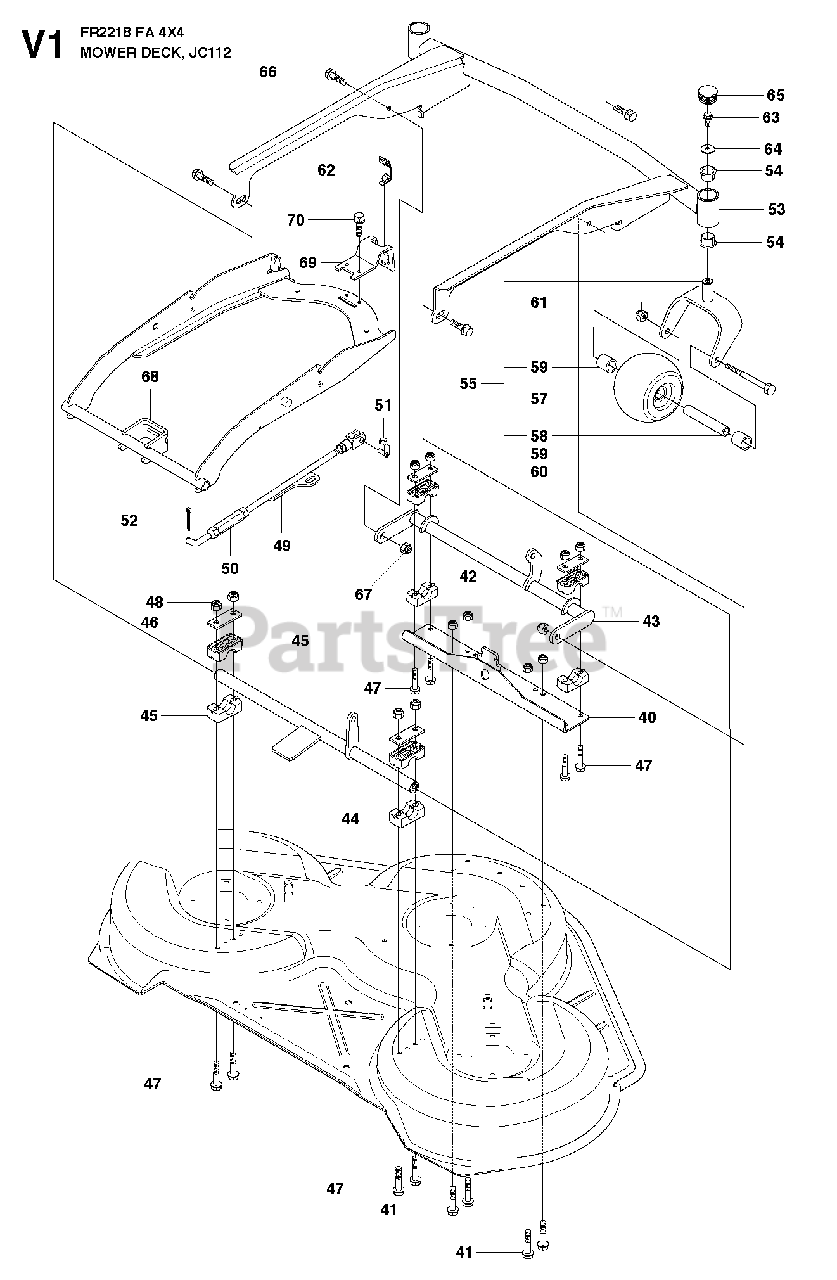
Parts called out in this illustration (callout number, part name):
42	LOCKNUT M8
48	LOCKNUT M8
49	PARALLELL ROD ASSY
50	PARALLEL ROD
51	RETAINER
52	SPLIT PIN
57	DECK ROLLER, FRONT
58	PIPE
59	SPACER
61	NUT
62	CLIP GRAY
67	LOCKNUT M8
